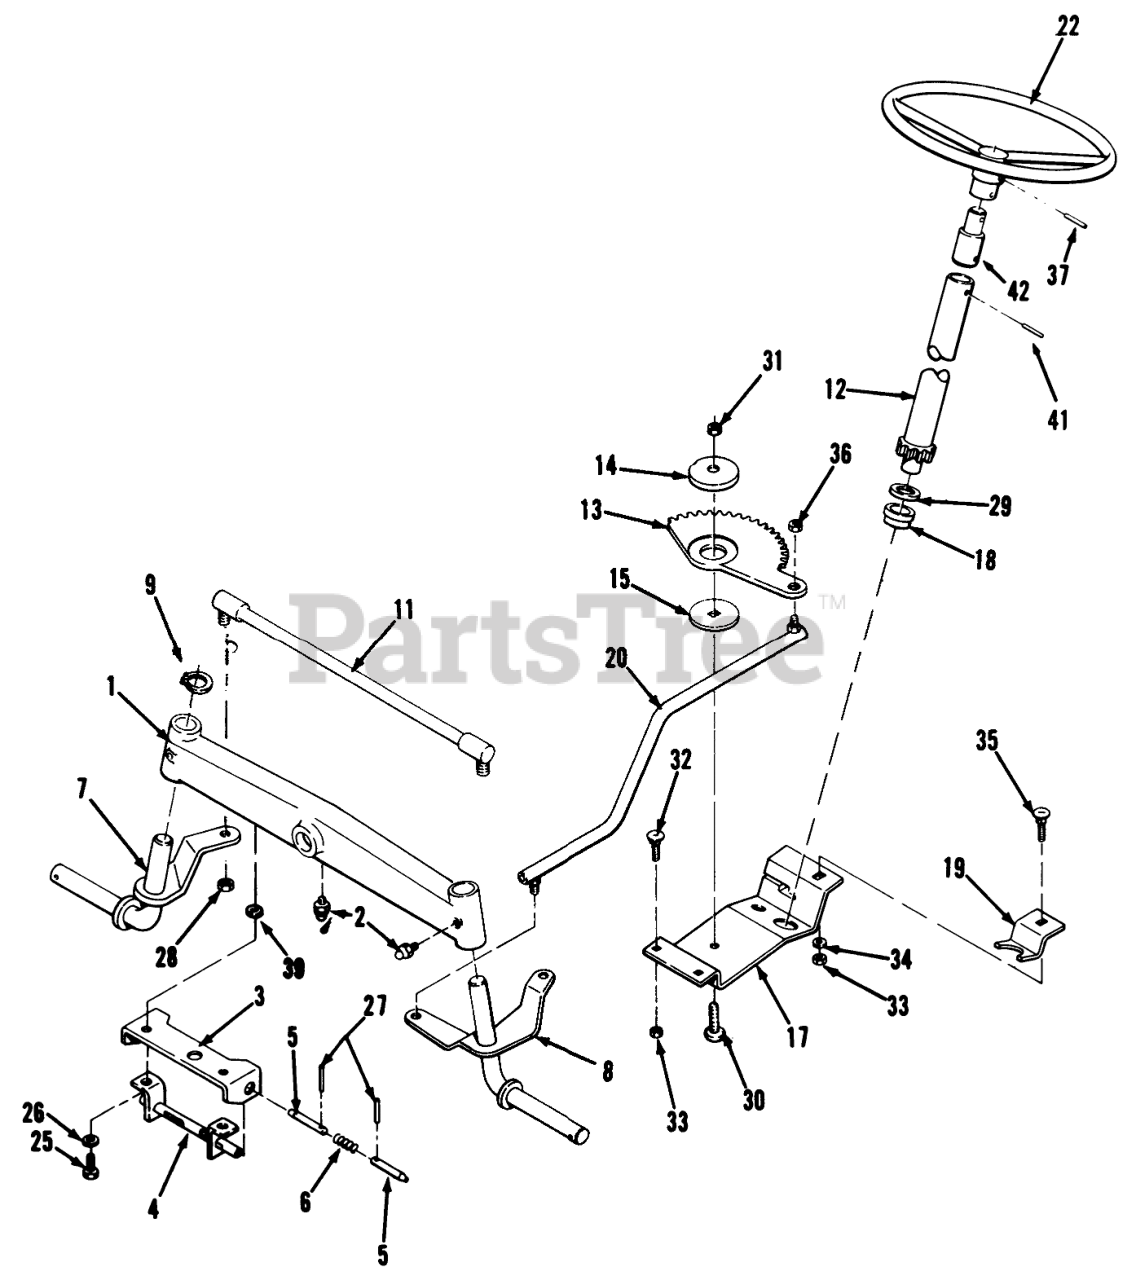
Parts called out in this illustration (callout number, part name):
1	AXLE-FRONT R
2	Zerk
3	BRACKET-SUPPORT R
4	TUBE & BRACKET ASM R
6	SPRING
7	ASSY ARM STEERING R
8	ASSY ARM STEERING R
9	Snap Ring
11	ASS'Y-TIE ROD R
12	ASSY PINION & SHA B
13	GEAR SECTOR
14	BUSHING
15	WASHER-BEARING
17	Steering Gear Bracket 212-5
18	BEARING-WHEEL
19	RETAINER R (NS)
20	ASSY BALL JOINT L R
22	Steering Wheel
25	HHCS
26	Lockwasher
27	SPIROL PIN
28	5/16-24 E.S. NUT
29	SHIM-WASHER
30	Bolt-Carriage
32	Bolt
33	Nut
34	WASHER 5/16 SAE
35	Collar
36	NUT-6
37	SPIROL PIN 5/16X13/8
39	WASHER
41	Pin-Roll
42	SHAFT-COUPLER
